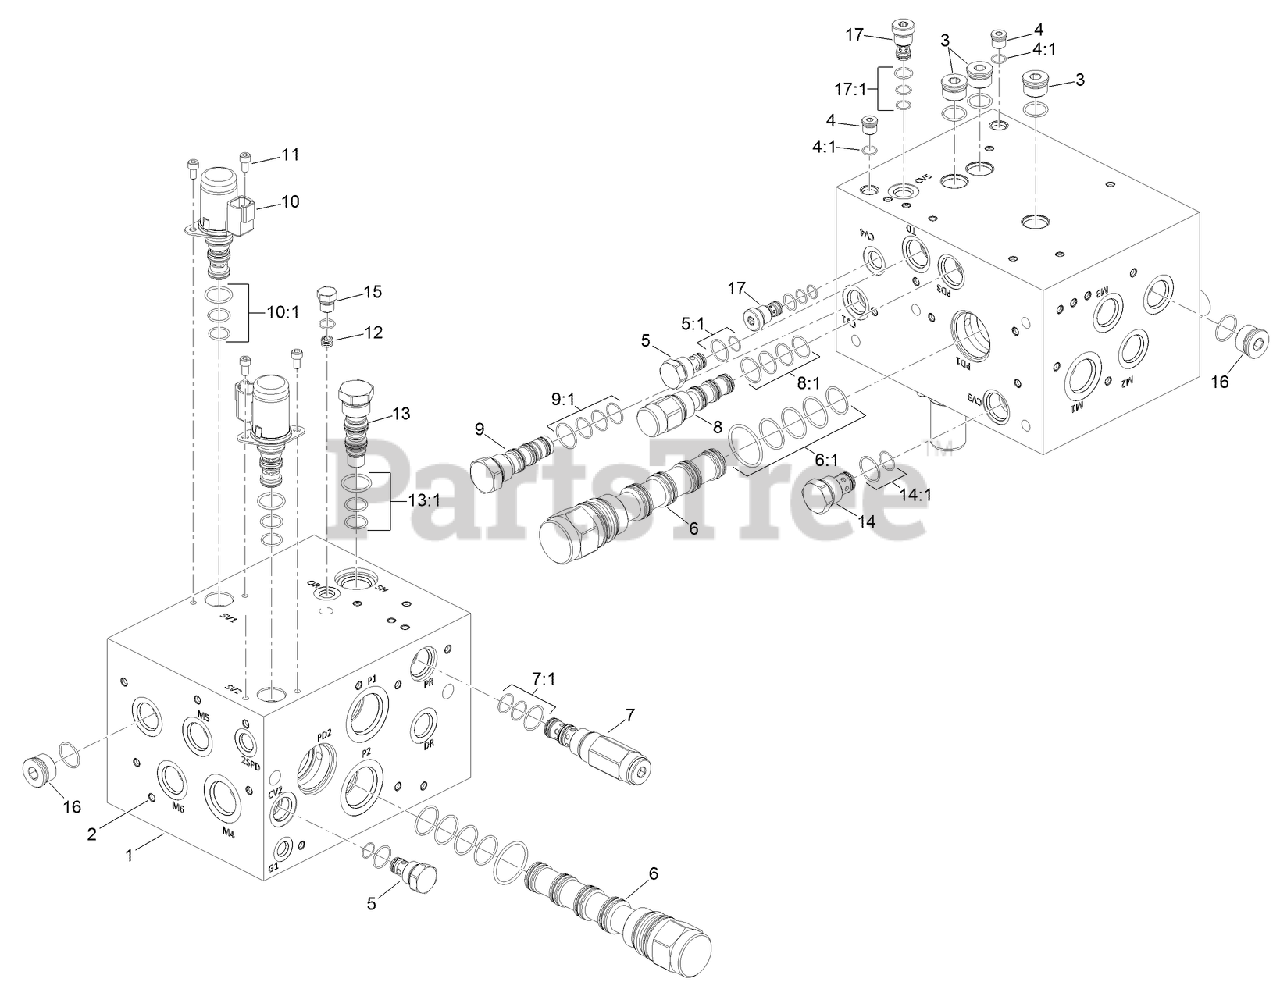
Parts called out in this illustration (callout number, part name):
1	BLOCK-MANIFOLD
2	Deck ASM
3	PLUG-HYD
4	PLUG ASM
4:1	O-RING
5	CHECK VALVE ASM
5:1	SEAL KIT
6	VALVE-BIAS, PILOTED WAY
6:1	SEAL KIT
7	VALVE-REDUCING, PRESSURE
7:1	SEAL KIT
8	VENT-EXTERNAL, PILOTED
8:1	SPOOL VALVE SEAL KIT
9	VALVE-TORQUE DIVIDER
9:1	SEAL KIT
10	VALVE-SOLENOID
10:1	SEAL KIT
11	SCREW-CAP, SOC HD
12	ORIFICE
13	VALVE-SHUTTLE, LOW SIDE
13:1	SEAL KIT
14	VALVE-CHECK, 180 PSI
14:1	SEAL KIT
16	PLUG-LEAK, ZERO
17	VALVE-POPPET
17:1	SEAL KIT
